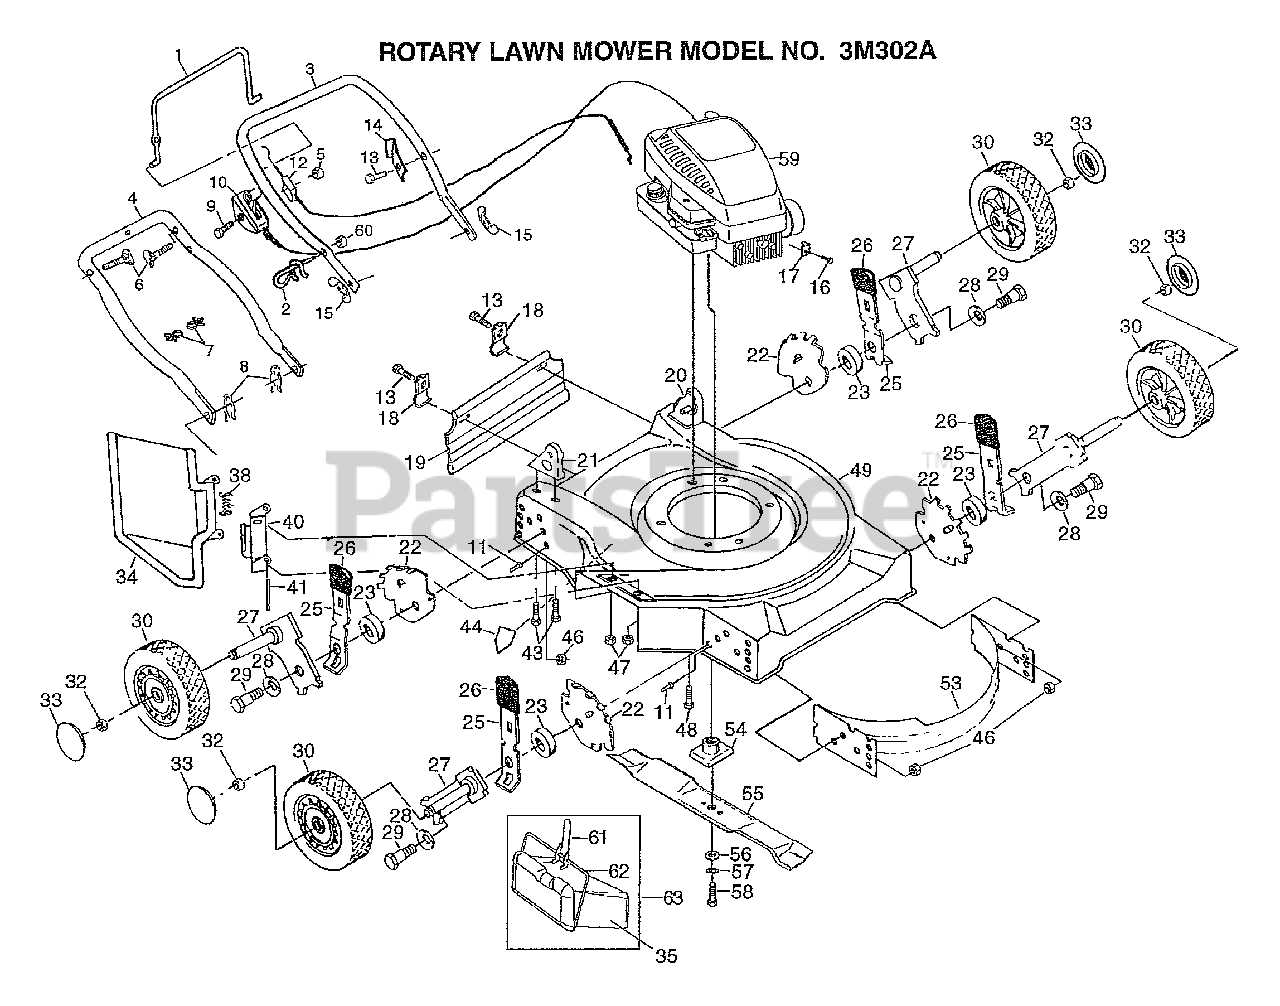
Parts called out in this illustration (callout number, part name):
1	CONTROL BAR
2	ROPE GUIDE
4	LOWER HANDLE
6	BOLT.HANDLE.LM
8	HAIRPIN COTTER
9	SCREW.HXHD.WASH.
10	"CONTROL, THROTTLE"
11	BLIND RIVET
12	"CABLE,ENG ZONE CO"
13	TAPPING SCREW
14	"BRKT,UPSTOP"
15	"NUT,WING PM"
16	SCREW PM
17	CABLE CLAMP
18	"BRKT,DEFL PM"
19	SKIRT.REAR.FGD.22
20	HDLE BRKT ASSY LH
21	HDLE BRKT ASSY.RH
22	BRACKET.ADJ.9POS.
23	SPACER.HEIGHT.ADJ
25	SPRING SELECTOR
26	KNOB PM
27	ARM.AXLE.ASM.BZP.
28	"WASHER, BELLEVIL."
29	BOLT SHLD 3/8-16
30	WHEEL.8X1.75.WHT
32	HEX FLANGE LOCKNT
33	HUB CAP
34	GUARD.DISCH.22SD.
35	MULCHER PLUG
38	SPRING.HINGE
40	BRACKET.HINGE.W/F
41	ROD.HINGE.COMBI-C
43	SCREW 5/16-18X3/4
44	DECAL HYT
46	LOCKNUT PM
48	BOLT.ENG.3/8-16
49	KIT.HSG.22SD.PUSH
53	BAFFLE.FRT/REAR
54	BLADE ADAPTOR
55	"BLADE.MULCH.22"""
56	"WASHER,HARDEN"
57	LOCKWASHER
58	SCREW
60	NUT
61	LATCH.BAIL.MULCH.
62	MULCHER BAIL
63	PLUG.MULCHING.ASM
